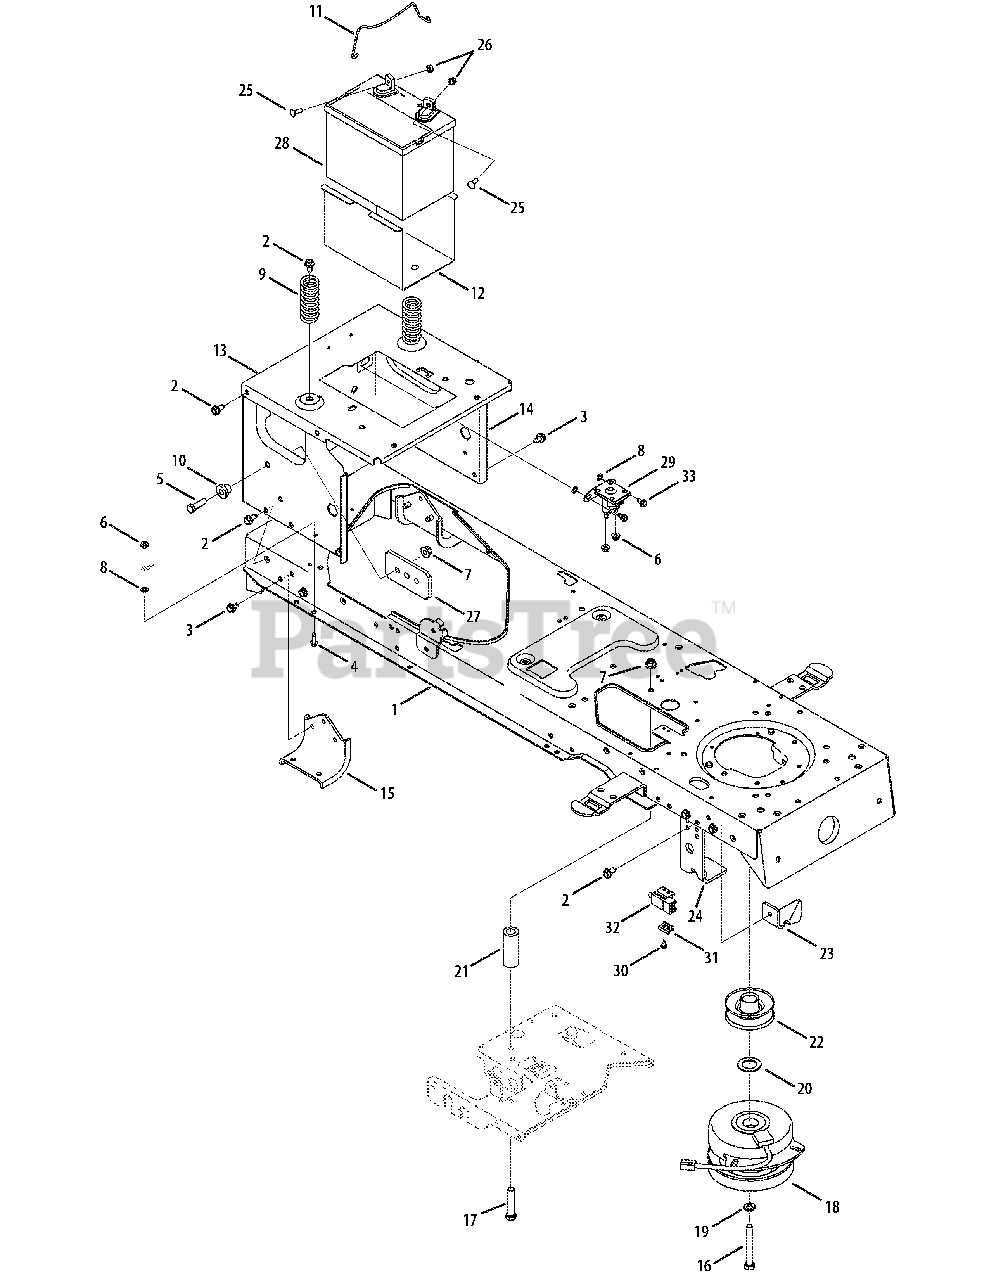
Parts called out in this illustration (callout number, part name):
1	Frame Assembly, Lower
2	Screw, 5/16-18 x 0.75
3	Screw, 5/16-18, 0.500
4	Screw, 1/4-20, 0.750
5	Screw, 3/8-16, 1.25, Gr5
6	Nut, Flange Lock, 1/4-20
7	Nut, Flange Lock, 3/8-16
8	Washer, Lock, 1/4, External
9	Spring, Compress., 1.28 x 3.125
10	Spacer, Shoulder,.38 x 1.0 x.70
11	Hold Rod, Battery
12	Battery Tray
13	Seat Bracket, Frame
14	Frame, Upper
15	Axle Bracket
16	Screw, 7/16-20, 3.50, Gr5, Lock
17	Screw, 3/8-16, 2.25, Gr5
18	PTO Clutch, Electric
19	Lock Washer, 7/16
20	Washer, Flat, 1.031 x 1.620 x.095
21	Spacer,.385 ID x.635 OD x 1.54
22	Pulley, Engine, 3.56 Diameter
23	Clutch Bracket
24	Deck Bracket, Up-Stop
25	Hex Flange Bolt, 1/4-20,.75
26	Nut, Sems, 1/4-20
27	Support Plate
28	Battery, 235 CCA
29	Solenoid, 12V, 100 Amp
30	AB Screw, #10-16 x.500
31	Switch Plate
32	Switch
33	Screw, 1/4-20, 0.50
